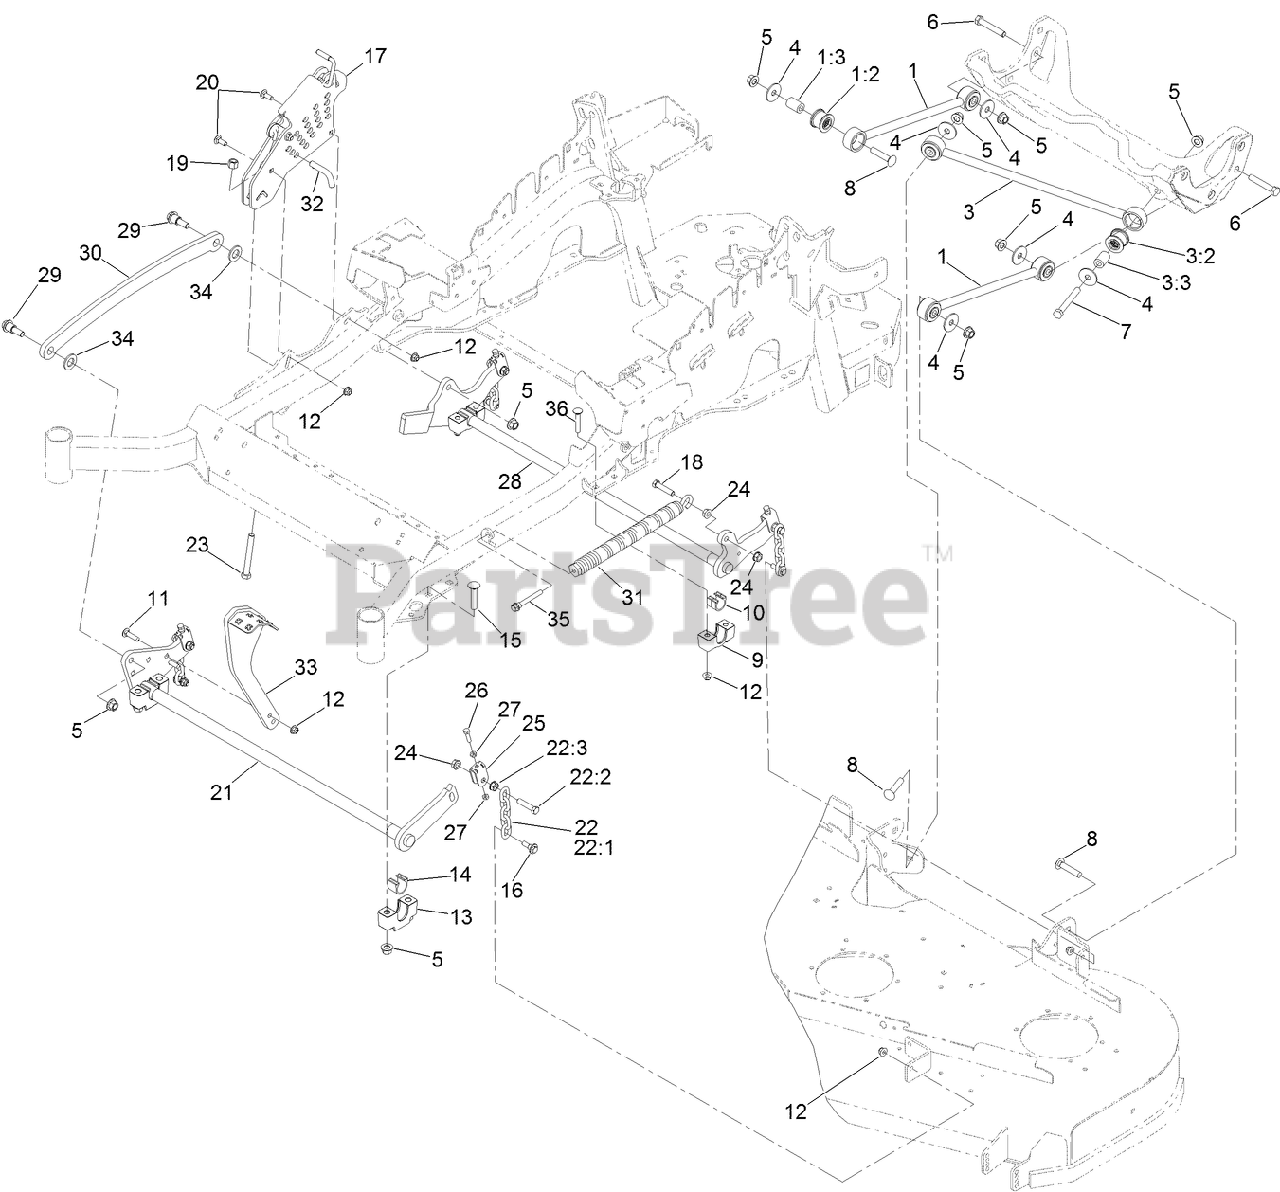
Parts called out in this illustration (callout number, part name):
1	DECK STRUT ASM
1:2	BUSHING-SUSPENSION, RUBBER
1:3	SPACER
3	PANHARD ROD ASM
3:2	BUSHING-SUSPENSION, RUBBER
3:3	SPACER
4	WASHER-THRUST
5	NUT-LOCK
6	SCREW-HH
7	SCREW-HH
8	SCREW-CARR
9	SUPPORT-CROSS SHAFT, BEARING REAR
10	BEARING-CROSS SHAFT, REAR
11	SCREW-HH
12	NUT-HF, NI
13	SUPPORT-CROSS SHAFT, BEARING
14	BEARING-CROSS SHAFT, FRONT
15	BOLT-CARR
16	SCREW-SHOULDER, HHF
17	HOC ASM
18	SCREW-HH
19	NUT-LOCK, NI
20	SCREW-HH
21	DECKLIFT-FRONT
22	DECK LIFT CHAIN ASM
22:1	CHAIN-LIFT, DECK
22:2	SCREW-HH
22:3	NUT-HF
23	BOLT-TAP
24	NUT-HF
25	YOKE-ADJUST, DECK
26	SCREW-HH
27	NUT-JAM
28	LIFT-DECK, REAR
29	SCREW-SHOULDER, HHF
30	LINK-LIFT, DECK
31	SPRING-EXTENSION
32	PIN-HOC
33	LEVER-FOOT
34	WASHER-FLAT
35	BOLT-SHOULDER
36	SCREW-HH
